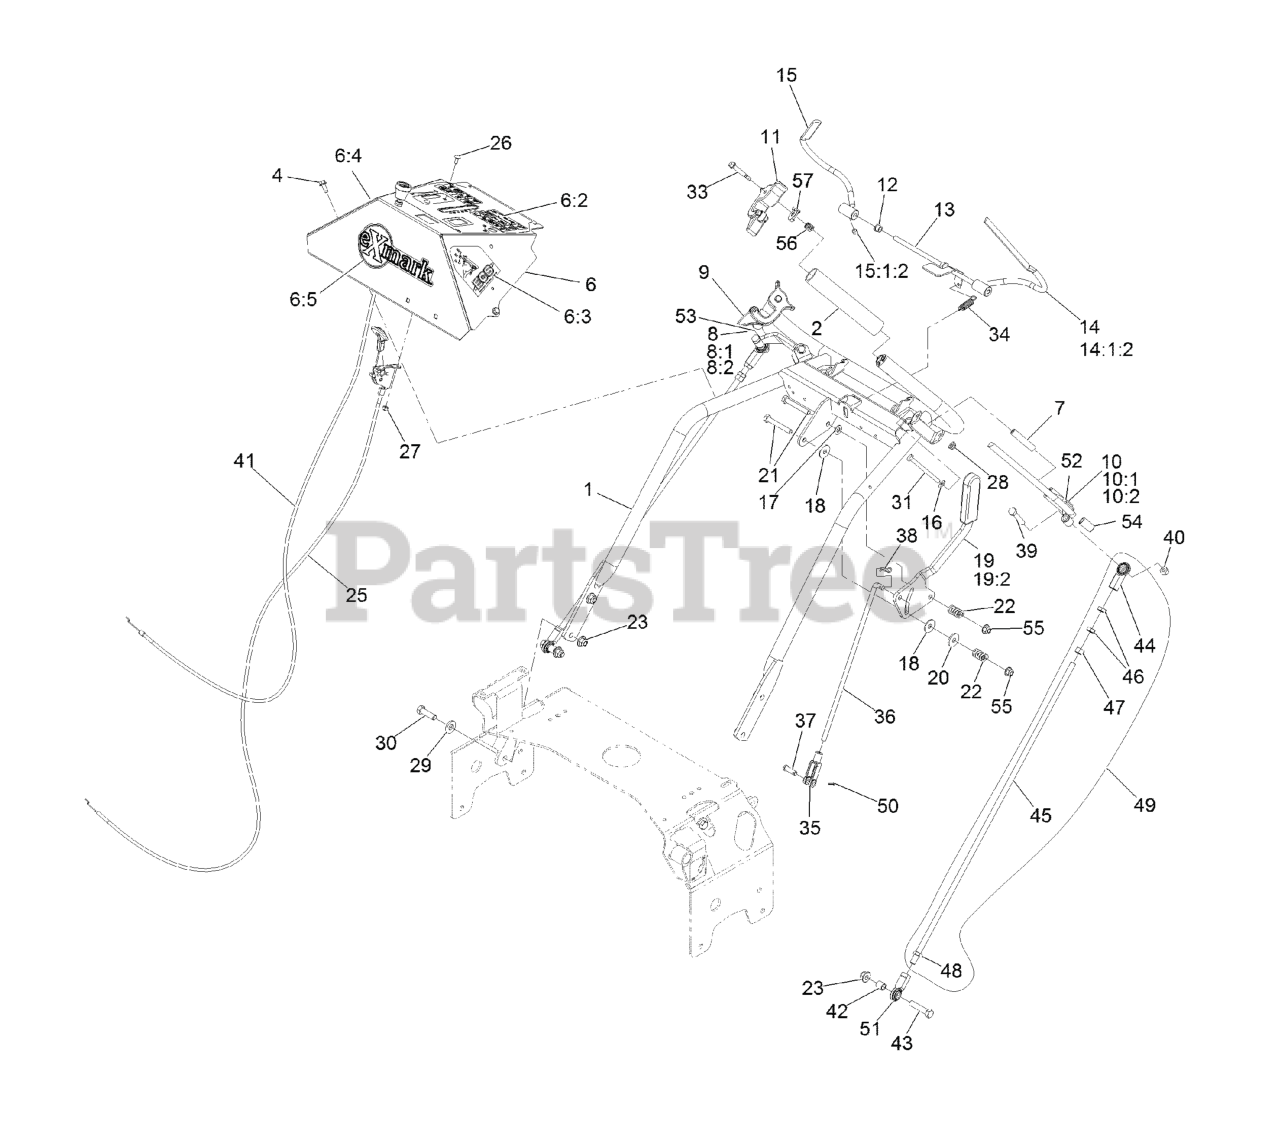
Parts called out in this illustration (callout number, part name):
1	WELD, HANDLE
2	GRIP-BAR, HANDLE
4	SCREW-HWH
6	ASM, CONSOLE W/ DECALS
6:2	DECAL-CONSOLE
6:3	DECAL,LH ECS INSTRUCTION
6:4	DECAL,RH ECS INSTRUCTION
6:5	DECAL, EXMARK LOGO
7	BUSHING-LEVER, DRIVE
8	DRIVE LEVER-ASM, RH
8:1	WLD,RH DRIVE LEVER
8:2	BUSHING, SLEEVE
9	ASM,LATCH RH THUMB
10	DRIVE LEVER-ASM, LH
10:1	WLD,LH DRIVE LEVER
10:2	BUSHING, SLEEVE
11	ASM,LATCH LH THUMB
12	BUSHING-NYLON
13	WLD,OPC LEVER AXLE
14	WLD,LH OPC LEVER
14:1:2	SCREW-SET
15	WLD,RH OPC LEVER
15:1:2	SCREW-SET
16	WASHER-FLAT
17	WASHER-PLAIN
18	WASHER-FRICTION
19	LEVER, SHIFT W/GRIP
19:2	GRIP-HANDLE, STEERING
20	WASHER-FRICTION
21	SCREW-HH
22	SPRING-COMPRESSION
23	NUT-HF, NI
25	CONTROL-THROTTLE
26	BOLT-CARR
27	NUT-LOCK, NI
29	WASHER-BELLEVILLE
30	SCREW-HH
31	SCREW-HH
33	SCREW-SHOULDER
34	SPRING-EXTENSION
35	YOKE-ADJUSTABLE
36	ROD,SPEED CONTROL
37	PIN-CLEVIS
38	PIN-COTTER
39	SCREW-HH
40	NUT-LOCK, NI
41	CABLE, CHOKE
42	SPACER-TUBE, PUMP LINK
43	SCREW-HH
44	JOINT-BALL, END
45	LINK,DRIVE (PLTD)
46	NUT-HJ
47	NUT-HEX
48	NUT-HEX JAM, LH
49	DRIVE LINK ASM
50	PIN-COTTER
51	JOINT-BALL END, LH
52	WLD,LH DRIVE LEVER
53	WLD,RH DRIVE LEVER
54	BUSHING, SLEEVE
55	NUT-HF, NI
56	SPRING-TANK, FUEL
57	LATCH, ECS
